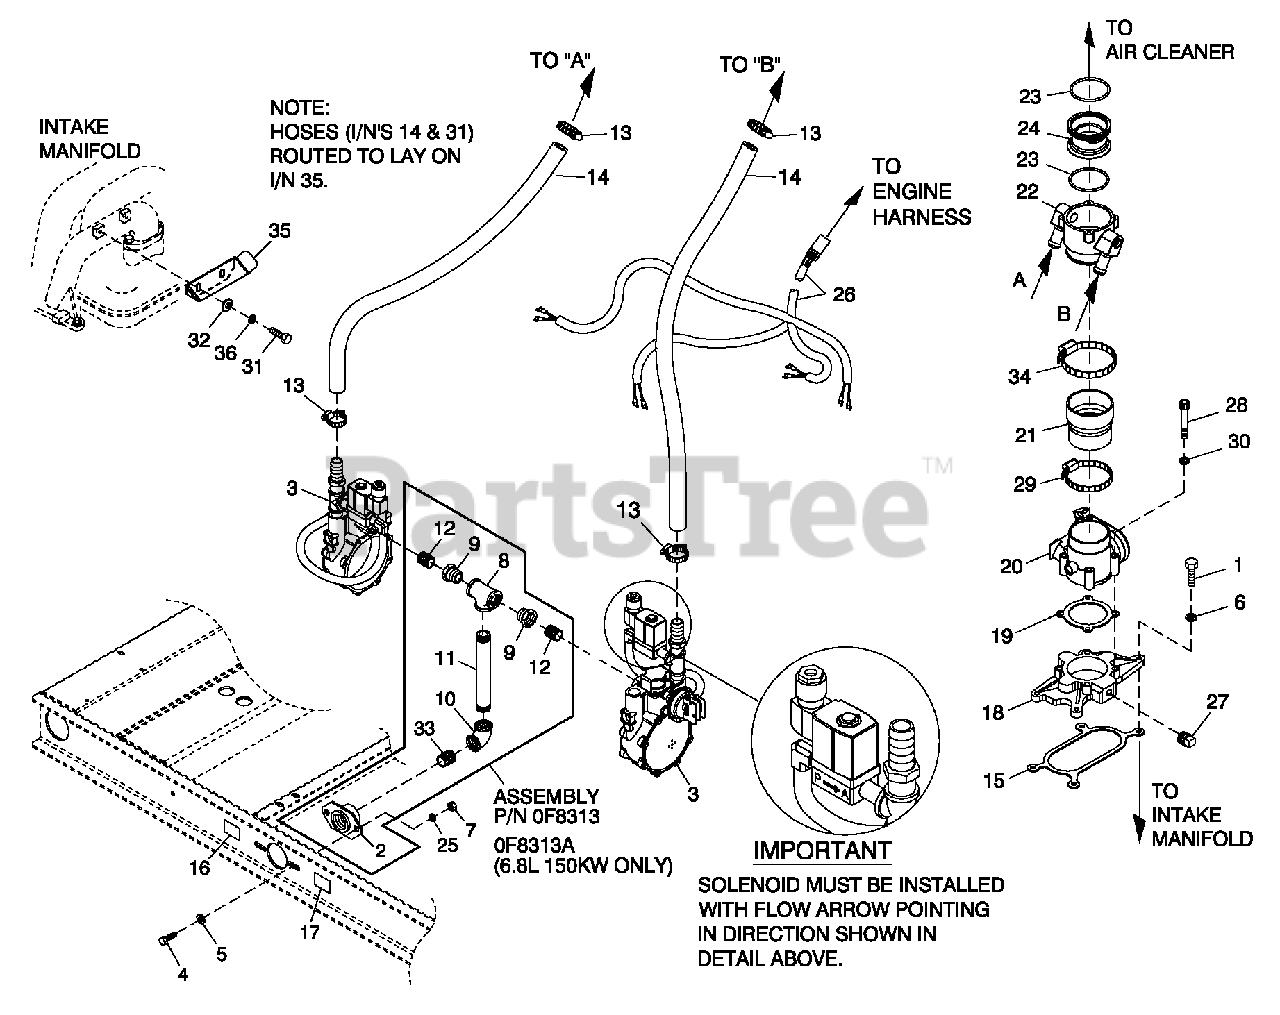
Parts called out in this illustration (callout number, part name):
1	SCREW HHC 5/16-18 X 1-1/4 G5
2	SUPPORT NAT GAS SOLENOID
3	REG ASSY 6.8L 130 KW DUAL LP QT
4	SCREW HHC M12-1.75 X 20 G8.8
5	WASHER FLAT 1/2 ZINC
6	WASHER LOCK M8-5/16
7	NUT HEX M12-1.75 G8 YEL CHR
8	PIPE TEE 1-1/4 NPT
9	BSHG RDCRHEX1-1/4-3/4
10	ELBOW 90D1-1/4 NPT
11	NIPPLE PIPE 1-1/4 NPT X 3 (100KW & 130 KW)
12	NIPPLE CLOSE 3/4 X 1.375
13	CLAMP HOSE #10 .56-1.06
14	HOSE 3/4 ID SAE-30R2 (45" LG)
15	GASKET ADAPTER THROT BODY
16	DECAL INLET PRESSURE
17	DECAL FUEL INLET LPG
18	ASSY,ADAPTER,THROTTLE BODY
19	GASKET GOVERNOR ACTUATOR
20	ACTUATOR BOSCH 60 GOVERNOR
21	REDUCER 3.0" TO 2.75" TURBO
22	MIXER 40/60MM ACTUATOR ASSY
23	O-RING 2-3/4X3/32X2-15/16
24	VENTURI THROTTLE 42MM (6.8L 100 KW)
25	WASHER LOCK 1/2
26	HARNESS, FUEL JUMPER DUAL REG
27	PLUG STD PIPE 1/4 STEEL SQ HD
28	SCREW SHC M6-1.0 X 50 C8.8
29	CLAMP HOSE #44 2.31-3.25
30	WASHER LOCK M6-1/4
31	SCREW HHC M6-1.0 X 20 G8.8
32	WASHER FLAT M6
33	NIPPLE CLOSE 1.25 NPT X 1.625
34	CLAMP HOSE #52 2.81-3.75
35	BRACKET, HOSE RISER
36	WASHER LOCK M6-1/4
